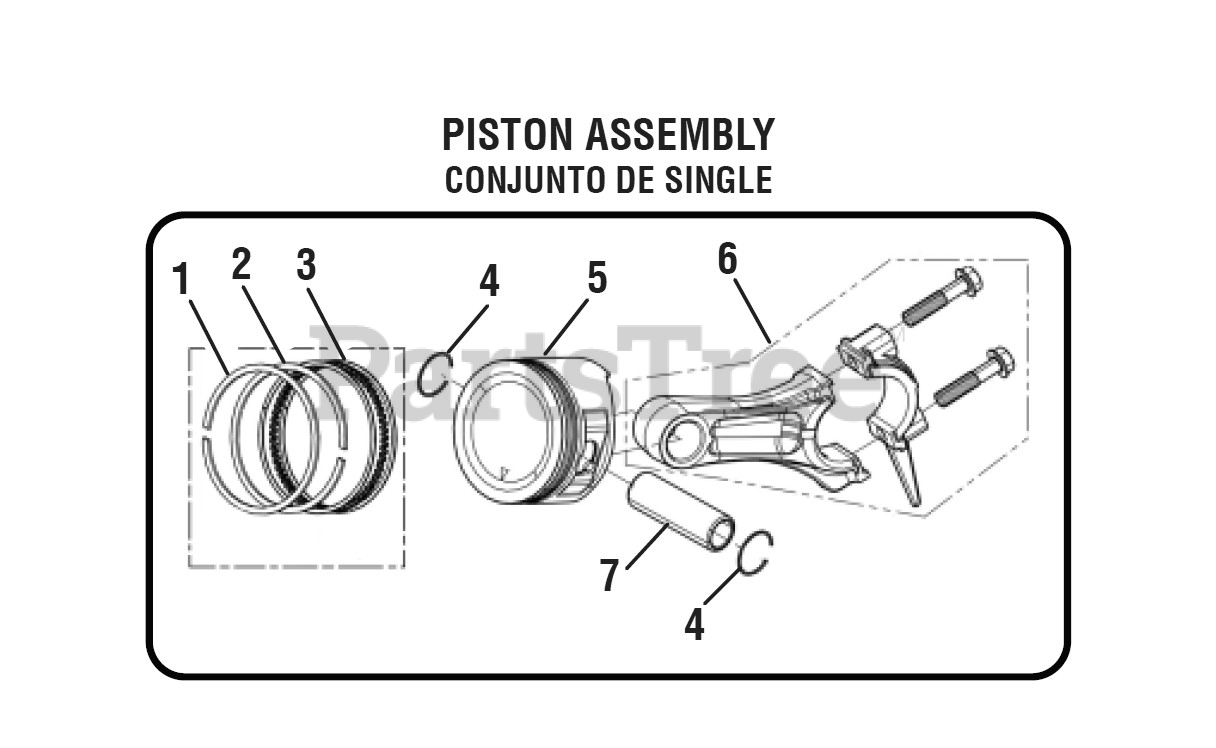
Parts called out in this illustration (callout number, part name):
1	The First Ring
2	The Second Ring
3	Oil Ring Kit
4	Piston Pin Clip
5	Piston
6	Connecting Rod
7	Piston Pin
